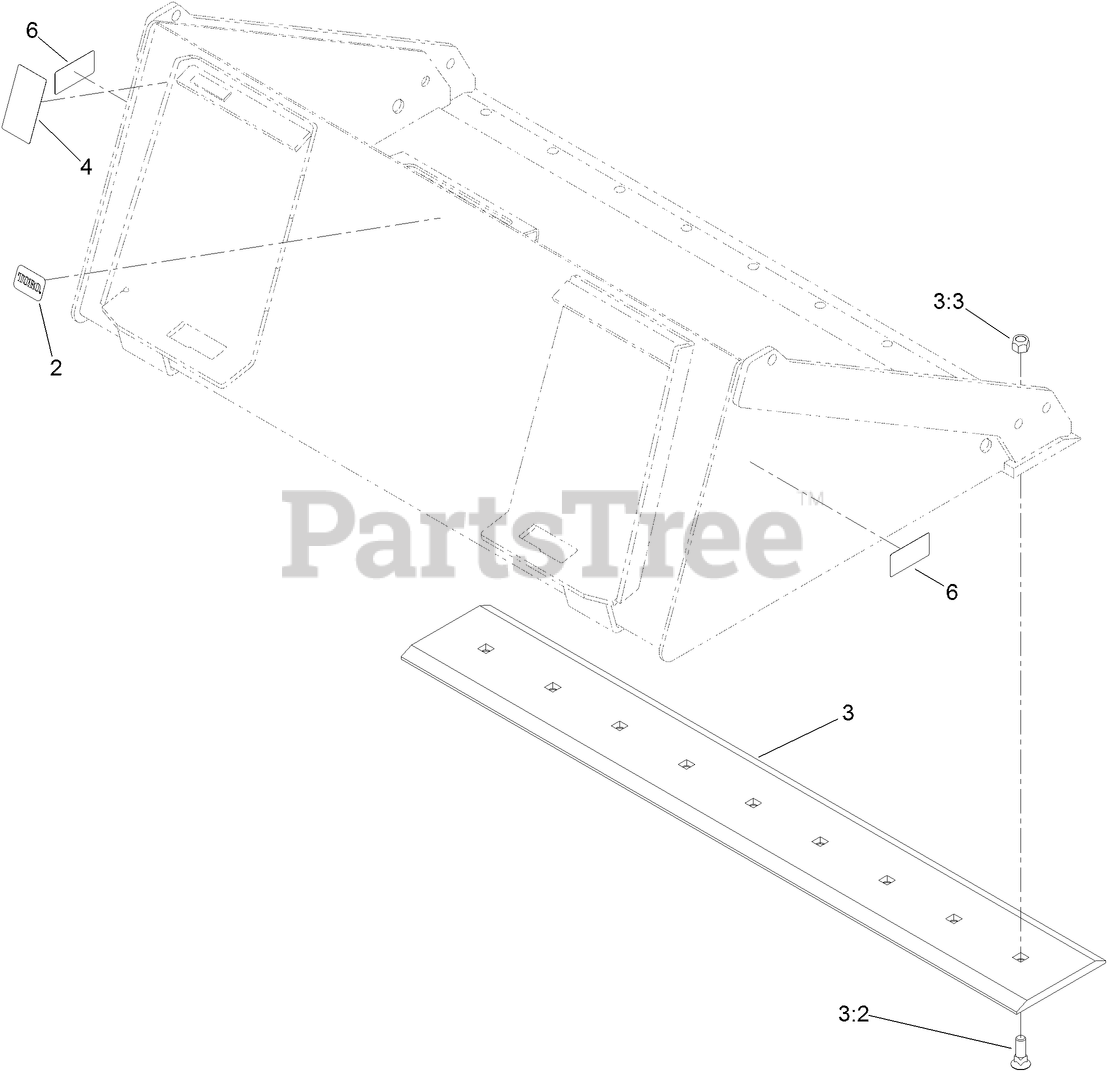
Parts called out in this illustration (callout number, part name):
2	DECAL
3	54IN BOLT ON EDGE KIT
3:2	BOLT-PLOW
3:3	NUT-LOCK, NI
4	DECAL-CAPACITY
6	DECAL-DANGER
